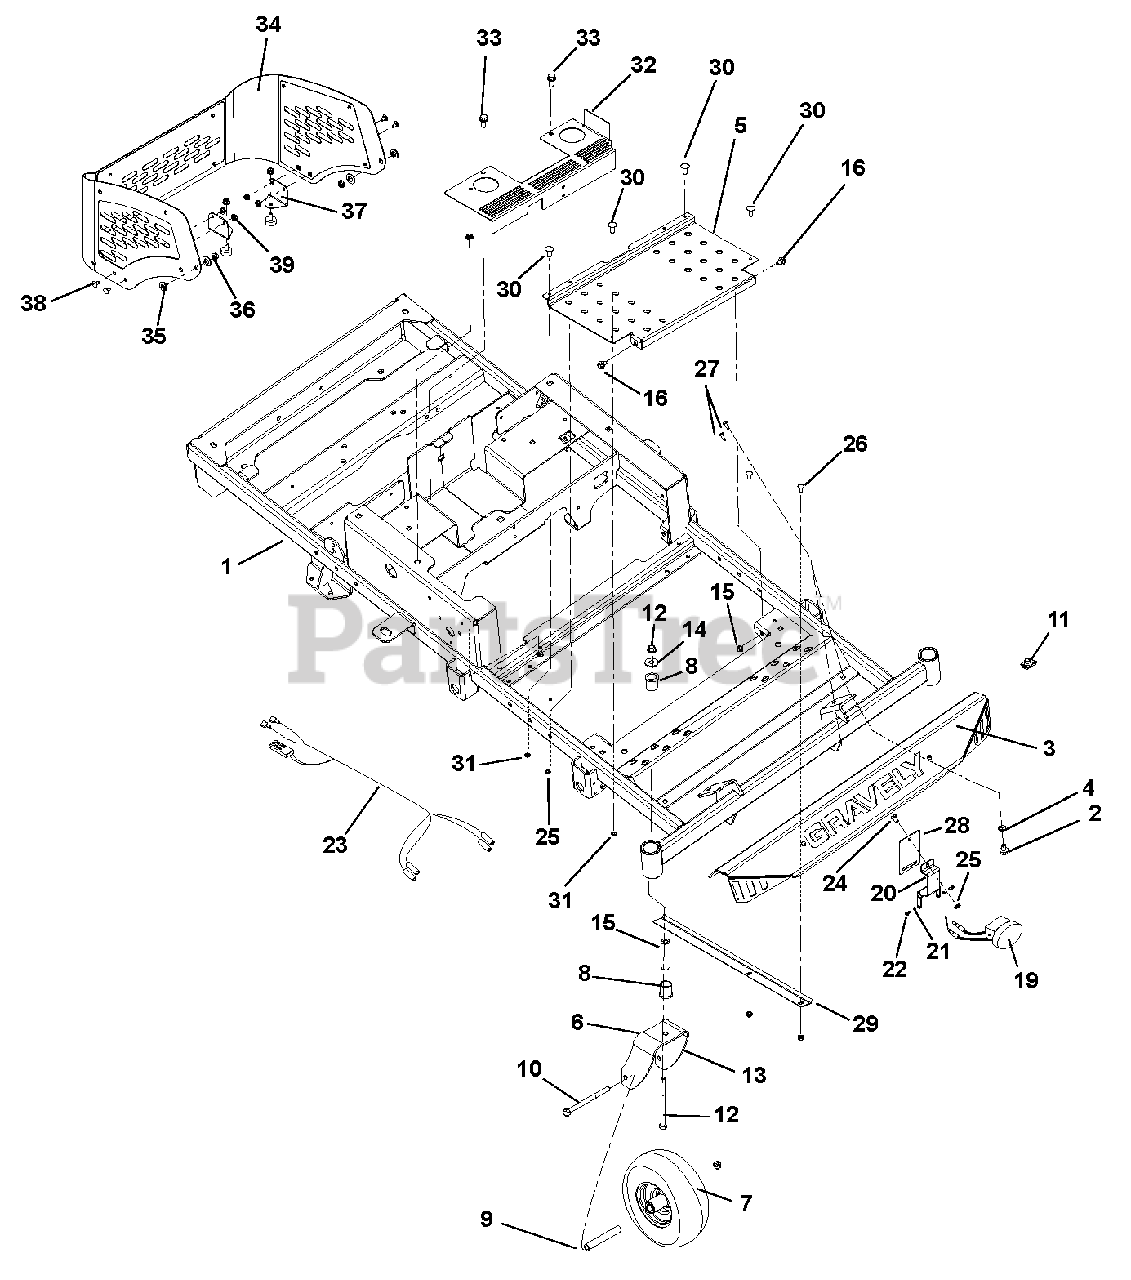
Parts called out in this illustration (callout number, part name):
1	Weldment, Frame XL
2	Bolt, Hex .38-16 x 1.00 Grade 5
3	Weldment, Footrest
4	Washer, Locking .38 x .094 Regular
5	Deck Access Panel
6	Fork, Caster
7	Wheel/Tire Assembly, 11.0 x 4.0 x 5.0, Monitor
8	Bushing, Flange 1.00 x 1.25 x 1.50 x 1.50
9	Spacer, Rolled Wheel
10	Bolt, Hex .50-13 x 6.50 Grade 5
11	Nut, Retainer .375-16 x .37
12	Nut, Locking Top Flange .50-13
13	Bolt, Hex .50-13 x 5.00 Grade 5
14	Washer, Flat Steel .511 x 1.441 x .125
15	Spacer, Caster Fork
16	Bumper, Rubber
17	Nut, Serrated Flange .31-18
18	Washer, Flat Nylon .52 x 1.00 x .08
19	Kit, Zoom/ZT XL Light
20	Bracket, Light
21	Washer, Locking 4MM x 1MM Regular Cone Lock
22	Screw, M4 x .07 x 8 Socket Head Cap
23	Harness, Mini-Z Headlight
24	Bolt, Round Head Square Neck .25-20 x .75 Grade 5
25	Nut, Top Lock Flange .25-20
26	Bolt, Round Head Square Neck .31-18 x .75 Grade 5
27	Bolt, Hex .25-20 x .75 Grade 5
28	Bracket, Light Mount
29	Bracket, Light Harness
30	Bolt, Hex .31-18 x 1.00 Grade 5
31	Nut, Locking-Nylon-Flange .31-18
32	Bracket, XL CE Fan Guard
33	Screw, Tapping .38-16 x .50 Hex Washer Head Thread Rolling
34	Assembly, Engine Wrap XL
35	Bushing, Flange .325 x .499 x .3 x .875
36	Nut, Locking Center Flange .31-18
37	Bracket, XL Engine Wrap Foot
38	Bolt, Round Head Square Neck .25-20 x .50
39	Nut, Locking Center Flange .25-20
